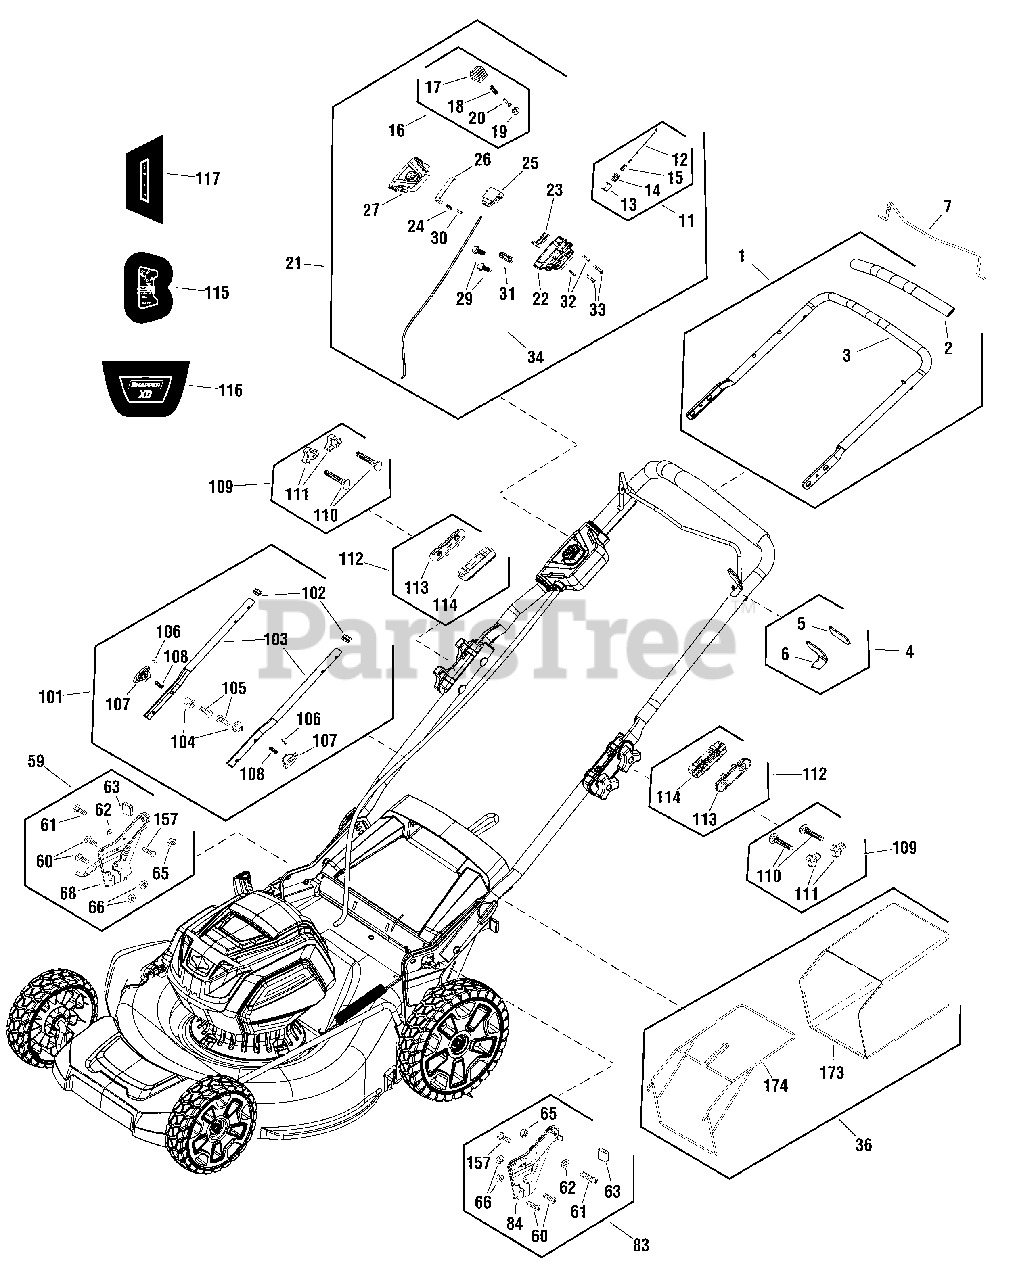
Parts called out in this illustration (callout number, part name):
1	KIT, UPPER HANDLE, NA
2	SPONGE
3	PUSH ROD, UP
4	KIT, STOP
5	SPONGE
6	PIECE, LIMIT
7	KIT, LEVER
11	KIT, CABLE ASSEMBLY
12	LASSO, THE START
13	SLIDER
14	SEAT, FIXED
15	SPRING
16	KIT, BUTTON
17	BUTTON, THE START
18	SPRING
19	GASKET
20	SCREW
21	KIT, SWITCH BOX COMPONENT, NA
22	COVER, DOWN
23	SLIDER, SWITCH
24	SPRING
25	SWITCH
26	BOARD, RIGID
27	COVER, UP
29	SCREW
30	SHAFT, SMALL
31	BOARD, LINE PRESSING
32	SCREW
33	SCREW
34	WIRE
36	KIT, GRASS BAGGER
59	KIT, RIGHT BRACKET, NA
60	BOLT
61	BOLT
62	GASKET
63	PLUG, RUBBER
64	HEIGHT ADJUST, RIGHT
65	NUT
66	NUT
83	KIT, LEFT BRACKET
84	HEIGHT ADJUST, LEFT
101	KIT, LOWER HANDLE
102	PLUG, RUBBER
103	ROB, DOWN PUSH
104	BLOCK
105	LIMIT COLUMN
106	PIN
107	KNOB
108	SPRING
109	KIT, HARDWARE
110	BOLT
111	KNOB
112	KIT, BOX, FIXED
113	MAIN BODY, FIXED BOX
114	COVER, FIXED BOX
115	DECAL, XD START
116	DECAL, XD SHROUD
117	DECAL, CHARGER INDICATOR
157	BLOCK
173	BAG, CLOTH
174	FRAME, GRASS BAG
